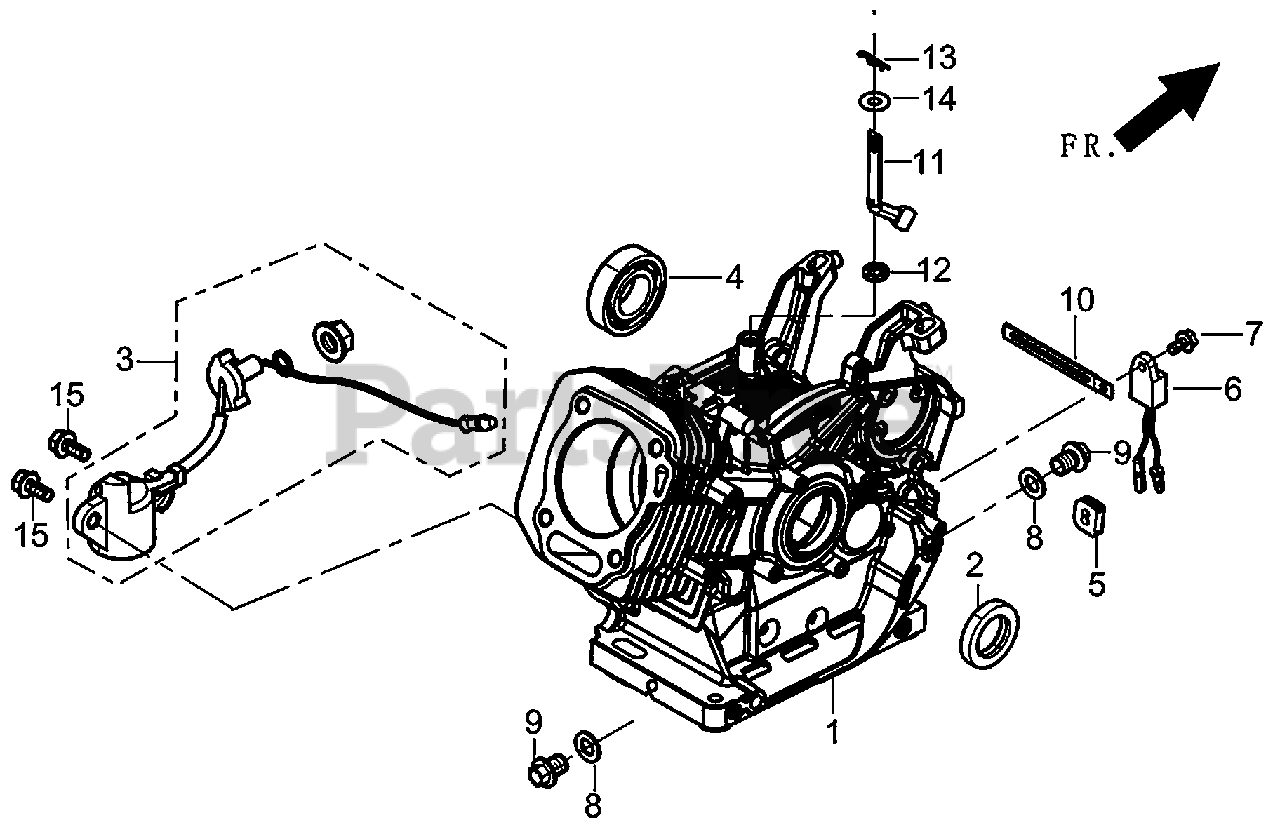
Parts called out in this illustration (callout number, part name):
1	CRANKCASE SUBASSEMBLY.
2	SEAL, OIL
3	SENSOR, ENGINE OIL
5	PLUG, RUBBER
6	PROTECTOR, OIL
8	WASHER FLAT
9	BOLT, DRAIN PLUG
11	ARM, GOVERNOR
12	SEAL, OIL
13	PIN, SPLIT
14	WASHER FLAT
